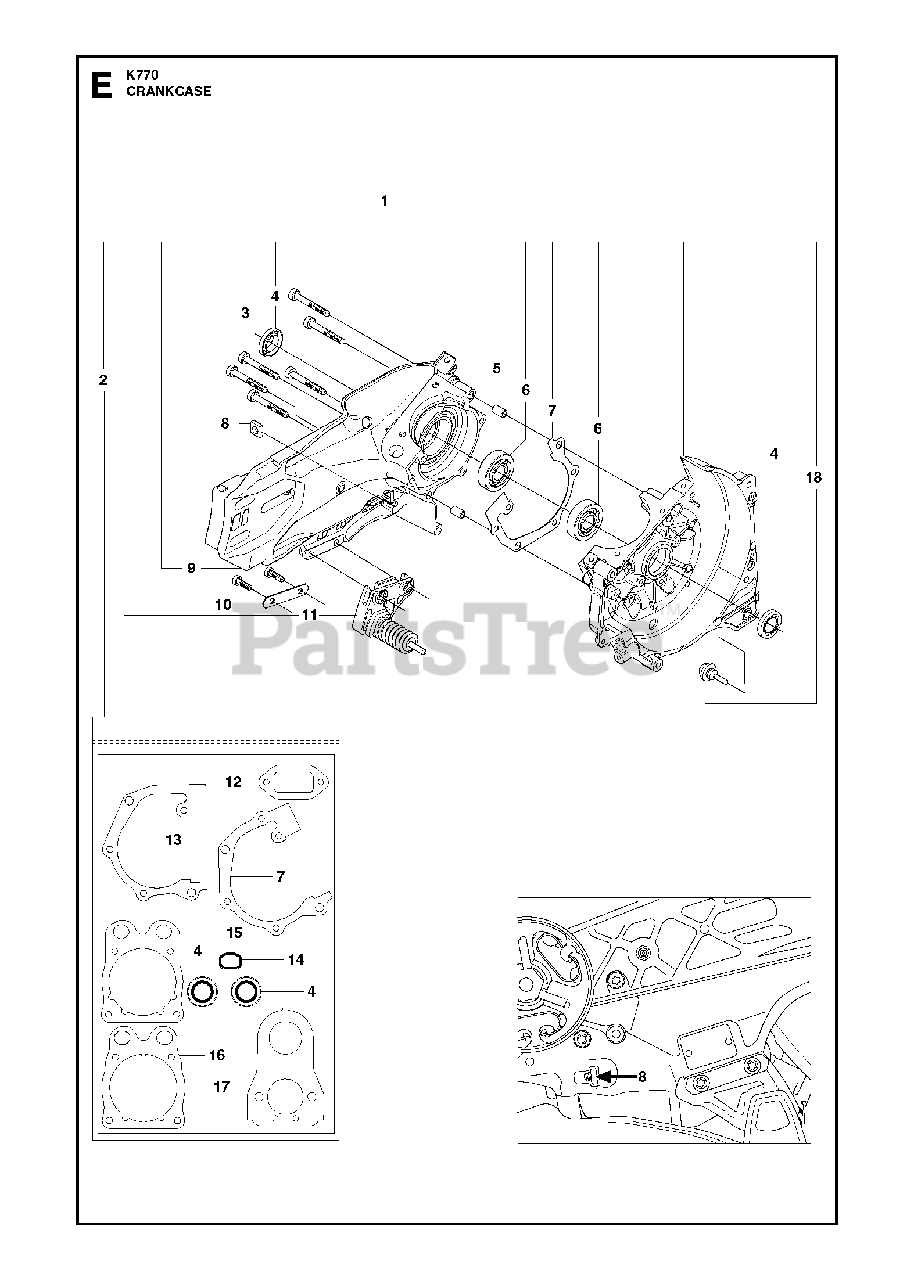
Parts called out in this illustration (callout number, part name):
1	CRANKCASE KITIncl. 2-7, 9-11, 18
2	GASKET KIT4, 7, 12-17
3	SCREW ITXSCM
4	SEALING RING
5	GUIDE BUSHING
6	BALL BEARING
7	GASKETSix hole
9	SCREW ITXSCM
13	GASKETFive hole
